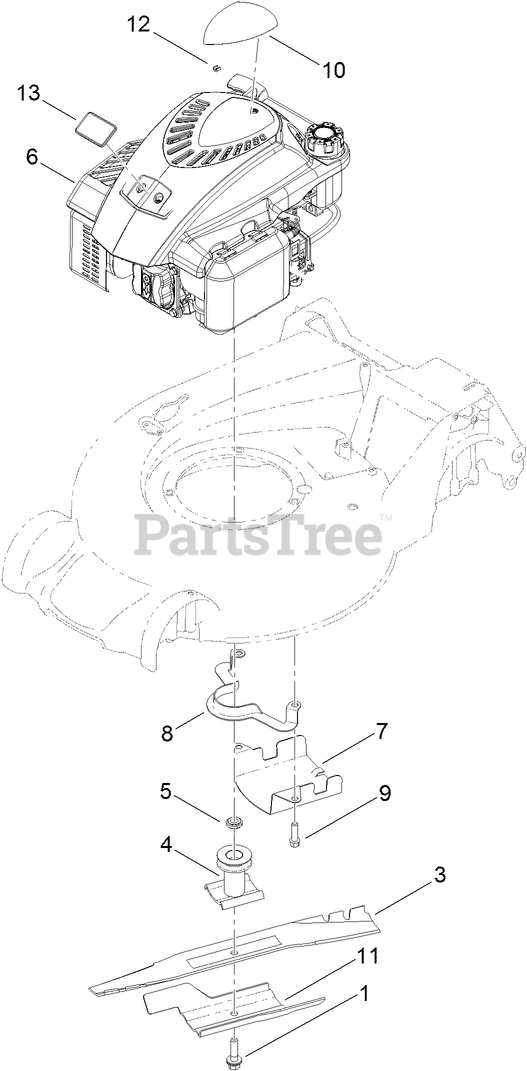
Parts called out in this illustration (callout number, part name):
1	BOLT-BLADE
4	DRIVER-BLADE
5	SPACER-DRIVER
7	SHIELD-GRASS
8	GUIDE-BELT
10	DECAL-SHROUD
11	ACCELERATOR-BLADE
12	STOP-ROPE
13	PLATE-LOGO
